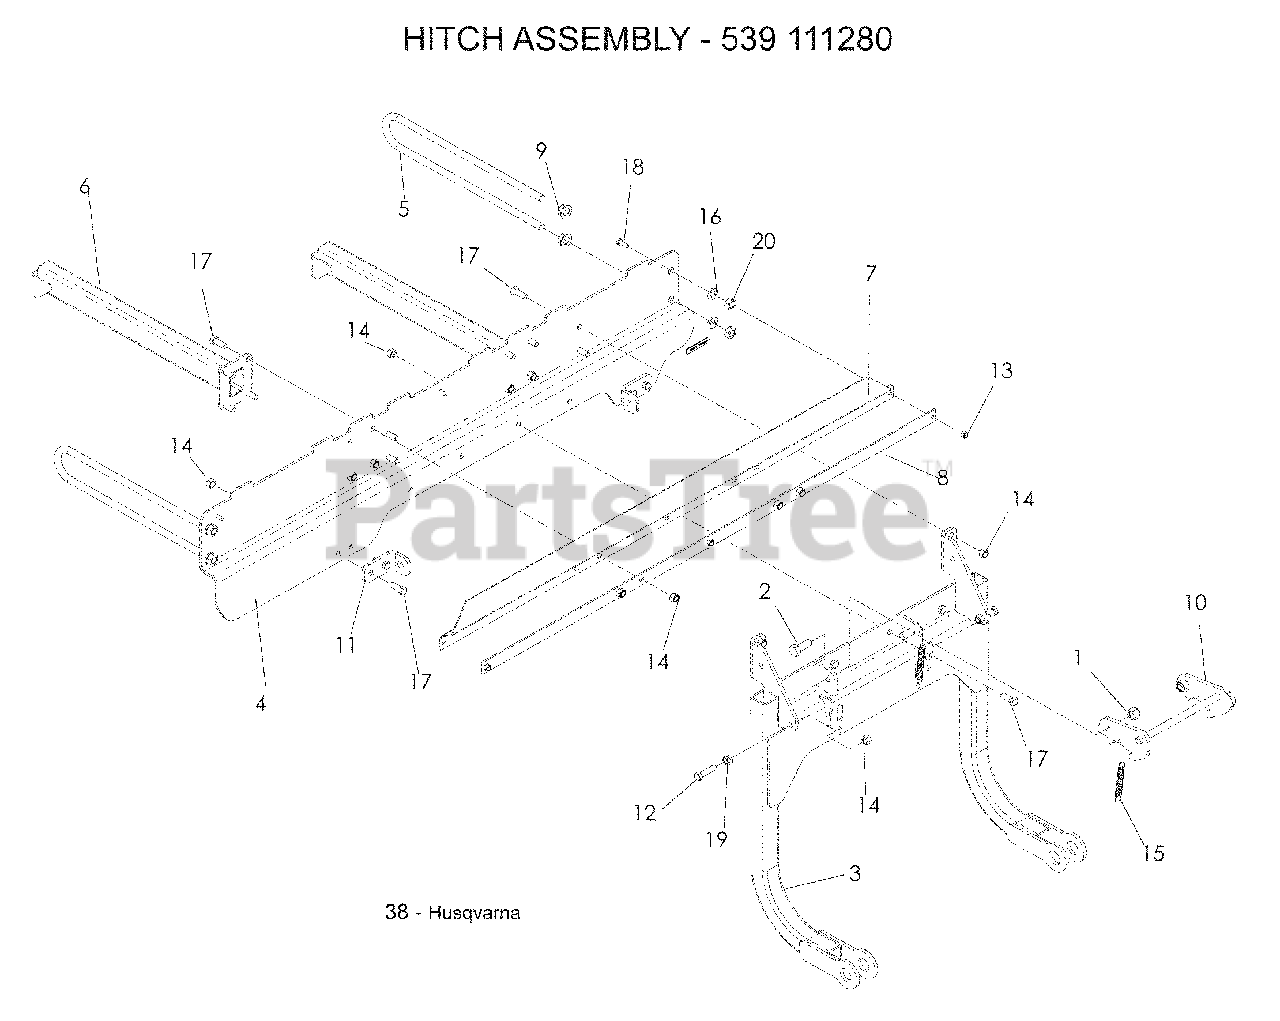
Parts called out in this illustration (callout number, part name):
1	NUT ½-13 HEX NYLOC
2	HCS ½-13 x 1¼
4	MOUNT Z BRACE
5	SUPPORT, OUTER
6	SUPPORT ARM
7	SEAL, RUBBER
8	SEAL STRAP
9	NUT ½ -13, WHIZLK
11	BRACKET, SUPPORT
12	HCS 3/8-16 x 1½
13	NUT ¼-20 HEX NYLOC
14	NUT 3/8-16 HEX NYLOC
16	LOCKWASHER ½
17	HCS 3/8-16 x 1
18	HCS ¼-20 x ¾
19	NUT 3/8-16 HEX WHIZLK
20	NUT ½-13 JAM
